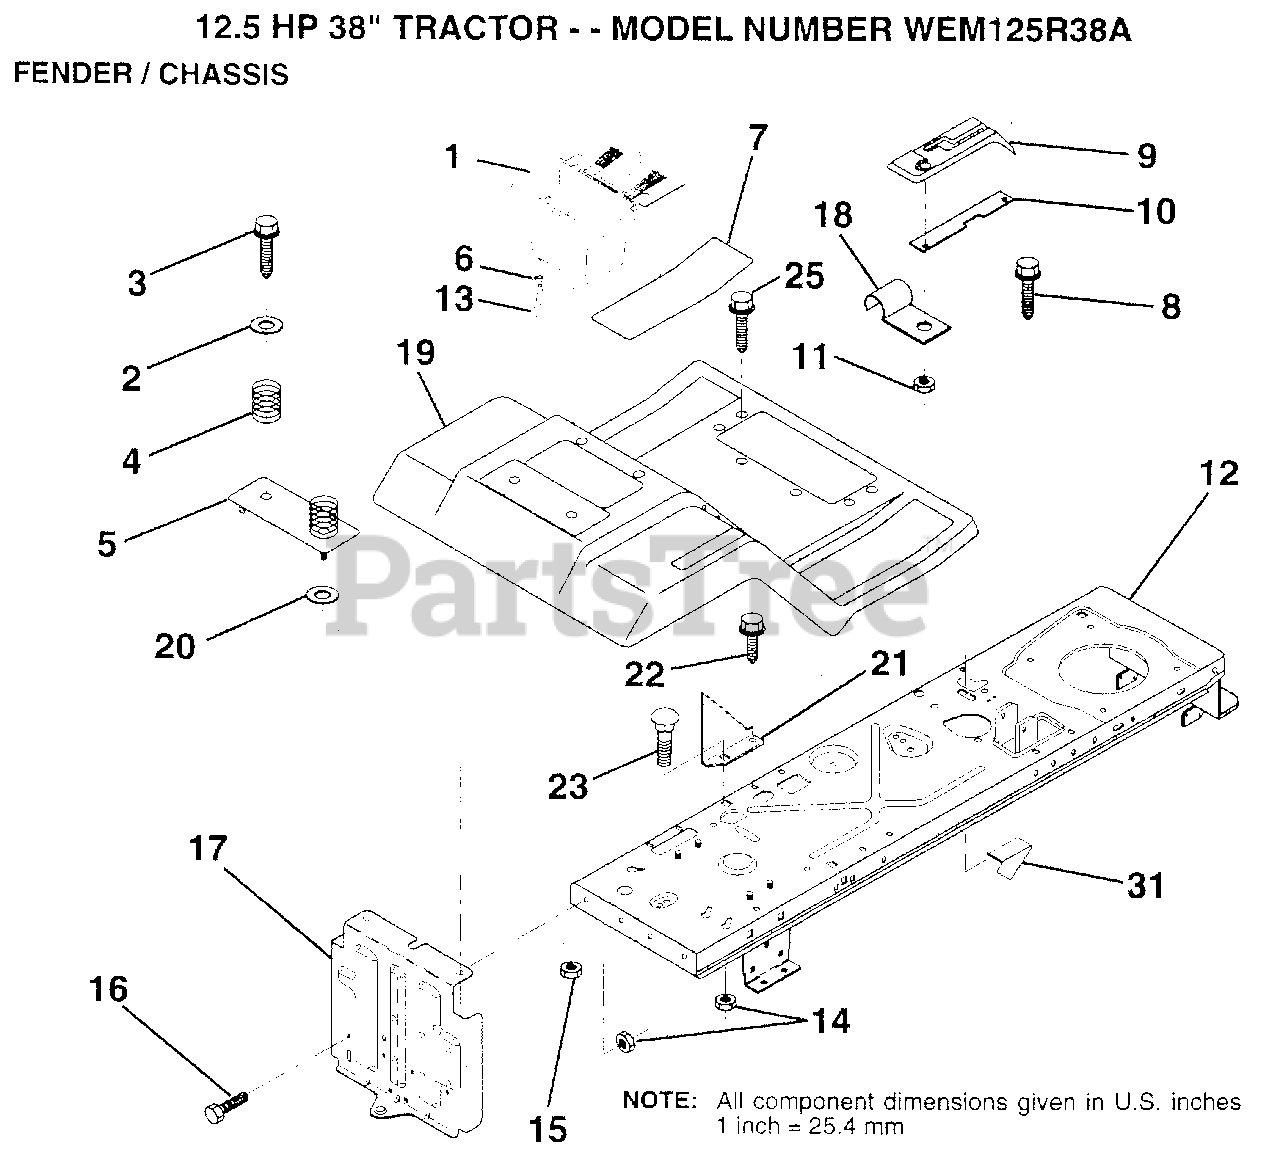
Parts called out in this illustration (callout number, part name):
2	WASHER
3	SCREW
4	SPRING COMPRESSIO
5	"PLATE, BATTERY"
6	HOSE CLAMP T
7	PAD FOOTREST
8	SCREW
10	PLATE LOCK SHIFT
11	NUT
13	TUBE T
14	NUT
15	NUT
16	BOLT
17	DRAWBAR ASM LR
18	"CLIP,INSULATOR"
19	FENDER/FOOTREST
21	BRACKET STOP DEPT
22	SCREW LT
23	BOLT, CARRIAGE 5/16-18X3/4
25	SCREW TI
